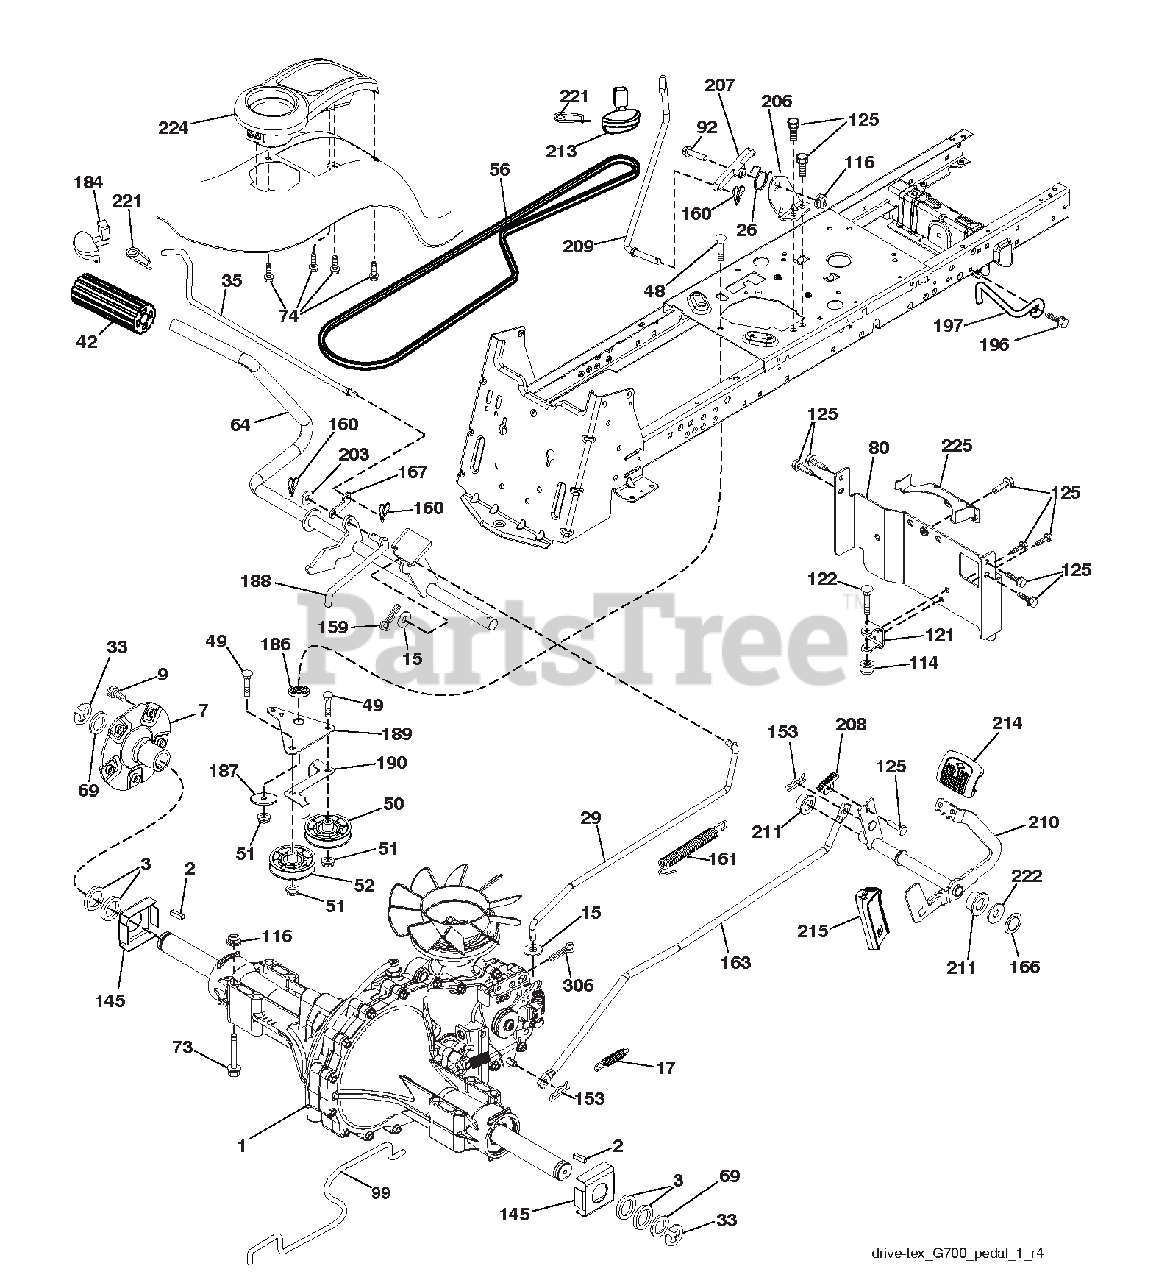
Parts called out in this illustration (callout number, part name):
2	KEY 1/4 X 2.5
3	WASHER THRUST AXLE HARDENED
7	HUB ASM. WHEEL
9	BOLT HUB WHEEL
15	WASHER.13/32 X 13/16 X 16 GA.
17	SPRING.BRAKE.GT.TEX
26	SPRING.RETURN.CRUISE
29	ROD.BRAKE
35	ROD.BRAKE.PARKING.LT.TEX
42	COVER PEDAL BLK ROUND
48	BOLT.CARR.SH.3/8-16X1-1/2.GR5
49	BOLT.RDHD.3/8-16UNCX1-3/4.GR5
50	IDLER.FLAT.910"OFFSET
51	Nut, Hex, Flangelock 3/8-16
52	IDLER.V-GROOVE.910"OFFSET
56	GROUND DRIVE BELT
64	SHAFT ASM.PEDAL.BRK.CNTRL.PCH
69	WASHER 1-1/32 X 1-5/8 X 16 GA.
73	BOLT.HEX. 5/16-18 X 3 GR. 5
74	SCREW.HEX.WSH.HI-LO.1/4X1/2UNC
80	STRAP.TORQUE
92	Bolt, Hex Head 5/16-18 x 1-1/4
99	SPRING.BYPASS
114	Locknut, Washer Insert 5/16-18
116	Nut, Lock Hex Flange 5/16-18 u
121	BRACKET.STRAP.TORQUE.T/A.3500
122	BOLT.5/16-18 x 2.50
125	SCREW.5/16-18X3/4.SMGML.TAP/BL
145	WASHER.AXLE.FLANGE
153	RETAINER SPRING
159	PIN.COTTER.1/8 X 3/4.CAD.
160	RETAINER.CLIP(M).DIA.290
161	SPRING.RETURN.CLUTCH.6.75
163	ROD.PEDAL.CONTROL
166	NUT PUSH .625
167	LATCH.BRAKE.PARKING
184	HANDLE.PARKNG.BRAKE.LT.TEX.667
186	SPACER.RETAINER
187	WASHER.13/32 X 2 X 10 GA.
188	LINK.CLUTCH.GROUND DRIVE
189	BELLCRANK.GROUND.DRIVE
190	KEEPER.BELLCRANK.GROUND.DRIVE
196	SCREW.3/8-16X1.SMGML.TAP/R.BLK
197	LINK CLUTCH ANTI-ROTATION
203	Washer 11/32 x 11/16 x 16 Ga.
206	BRACKET.MOUNT.LATCH.CRUISE
207	LATCH.CONTROL.CRUISE
208	GEAR SECTOR.CONTROL.CRUISE
209	ROD.CONTROL.CRUISE
210	ROCKER ASM. PEDAL CONTROL
211	BEARING.NYLON.BLK..629 ID.
213	KNOB.CONTROL.CRUISE
214	PAD PEDAL FORWARD
215	PEDAL.REVERSE
221	RETAINER.SPRING.CLIP.HANDLE
222	WASHER.21/32X1-1/4.10GA.N/PLTD
224	CONSOLE.TOOLBOX
225	KEEPER.BELT T/A
306	Pin Cotter 1/8 x 1 Cad
